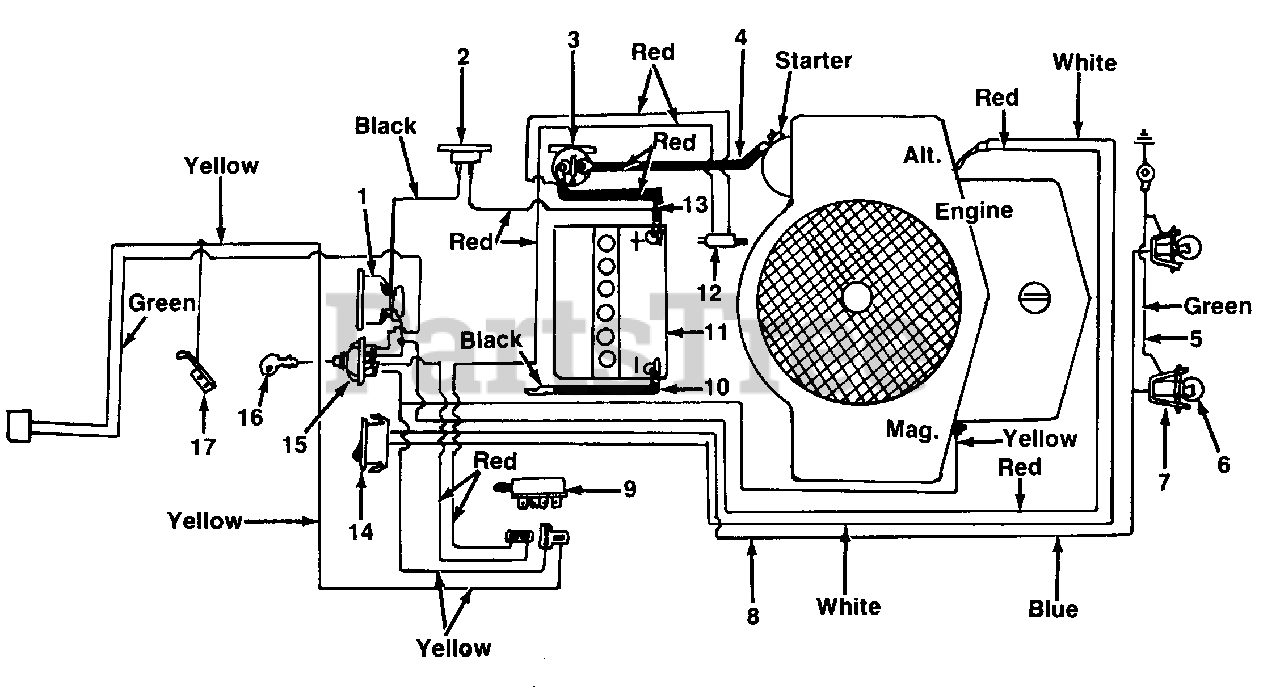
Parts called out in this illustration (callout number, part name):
1	Ammeter
2	Circuit Breaker
3	Solenoid
4	Electrical Cable
5	Double 14 x 5 Wire Lead
6	Lamp 12V
7	Twist Lock Lamp Socket
8	Wire Harness
9	Safety Switch-Blade
10	6 Ga. Elec. Wire Black-7.5" Lg.
11	Battery 12V
12	Safety Switch
13	Electric Wire
14	Headlight Switch
15	Ignition Switch
16	Ignition Key
17	Switch Spring
